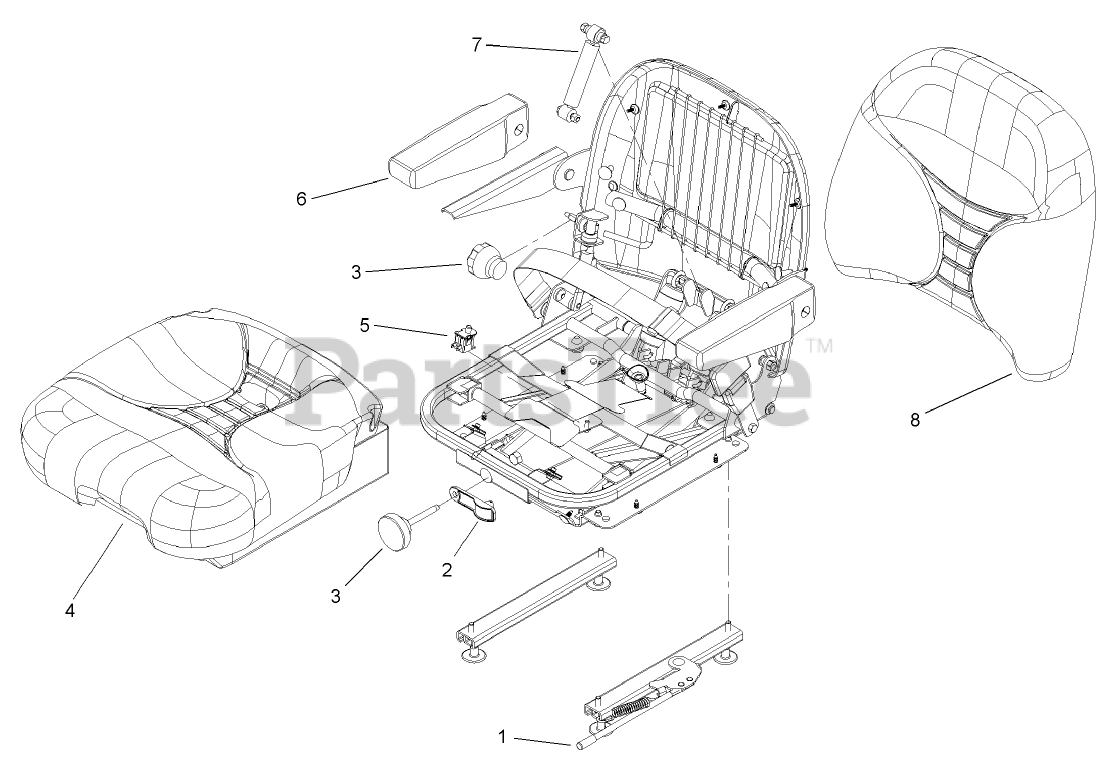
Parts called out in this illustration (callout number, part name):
1	Seat Track Kit
2	Weight Indicator Kit
3	Knob Kit
4	Bottom Cushion Kit
5	Switch Kit
6	PAD-ARMREST
7	Shock Absorber Kit
8	Back Cushion Kit
